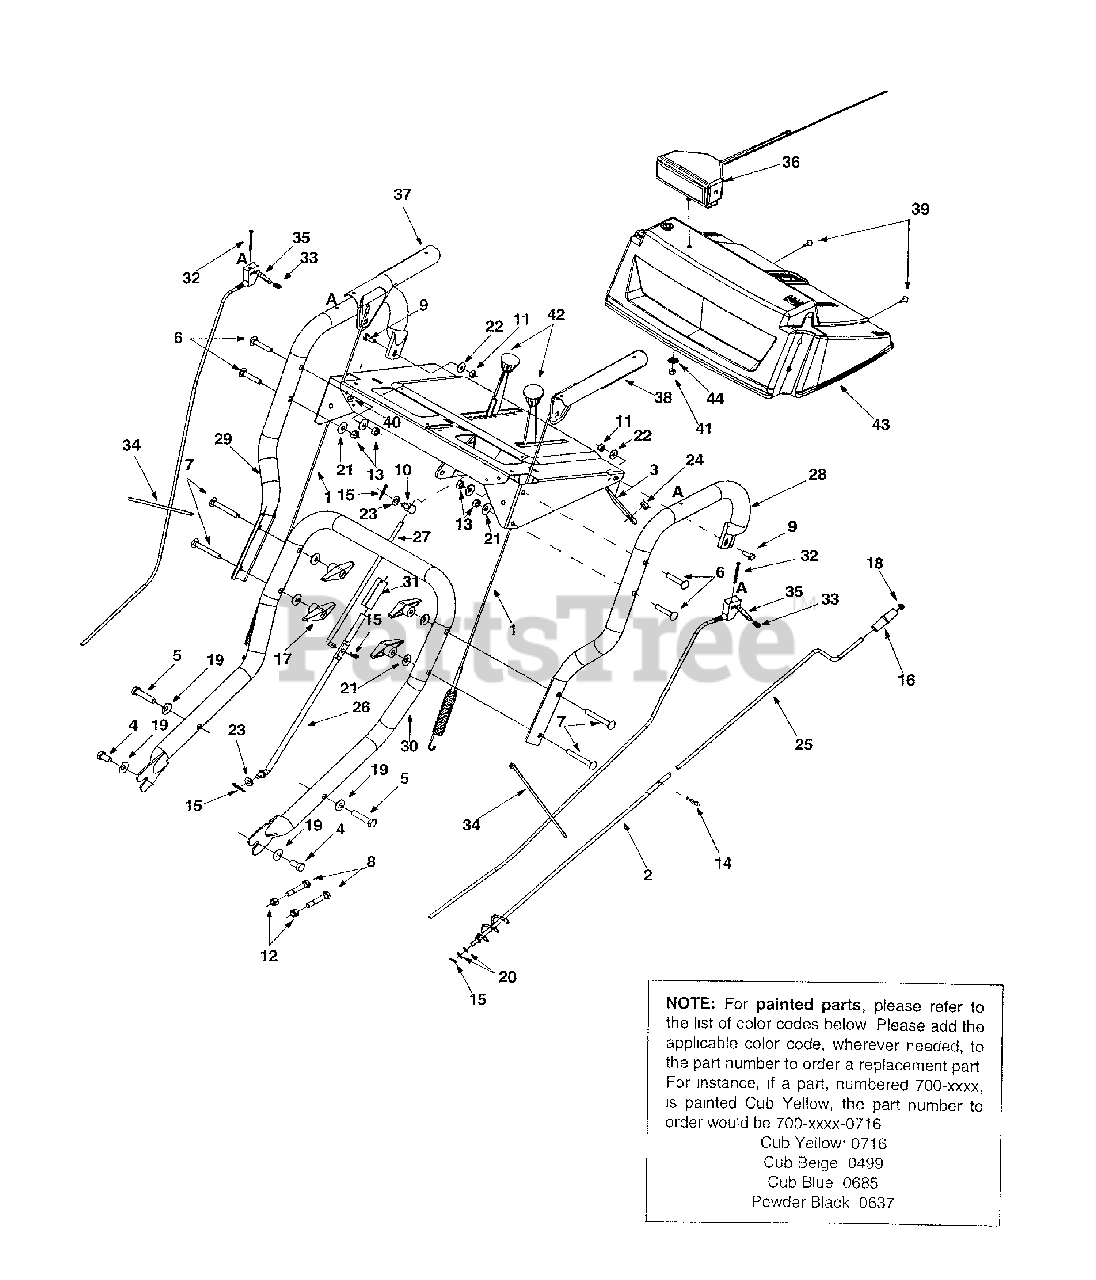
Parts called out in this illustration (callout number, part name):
1	Cable Assembly: Auger/Drive Engagement
4	Hex Screw 3/8-16 x .75"
5	Hex Screw 3/8-16 x 1.75"
6	Carriage Bolt 5/16-18 x 1.75"
7	Carriage Bolt 5/16-18 x 2.5"
8	Shear Bolt 5/16-18 x 1.75"
9	Hex Screw 1/4-20 x .75"
10	Ferrule
11	Hex Nut 1/4-20
12	Hex Lock Nut
14	Hairpin Clip
15	Hairpin Clip
16	Chute Crank Knob
19	Bell Washer
20	Flat Washer
21	Beleville Washer
22	Bell Washer
23	Flat Washer
24	Plastic Bushing
26	Lower Shift Rod
27	Upper Shift Rod
31	Clutch Rod Connector
32	Oval C-Sunk Screw
33	Flat Weld Nut
34	Cable Tie
35	Trigger Control
36	Light Assembly
37	Handle Engagement RH
38	Handle Engagement LH
39	Special B Screw
40	Hex Sems Nut
41	Hex Lock Nut
42	Shift Knob
43	Handle Panel
44	5/16 Washer
